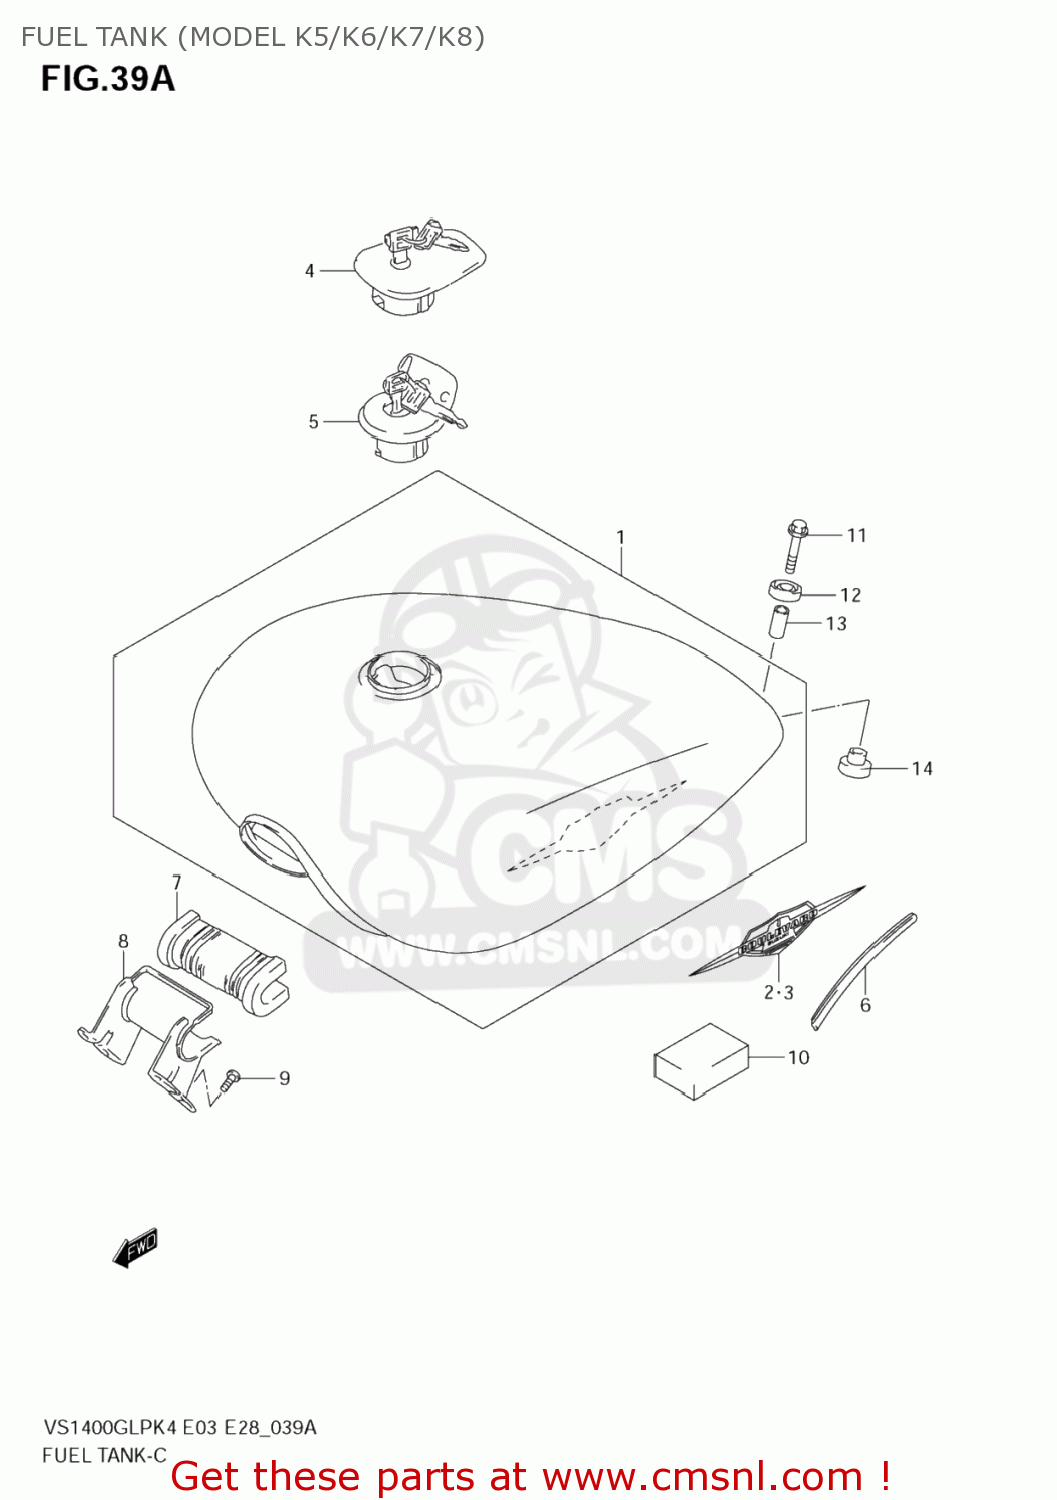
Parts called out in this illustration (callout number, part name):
1	TANK ASSY,FUEL(RED)
2	EMBLEM,FUEL TANK,R
3	EMBLEM,FUEL TANK,L
4	CAP SET,FUEL TANK
5	CAP SET,FUEL TANK
6	MOLDING
7	CUSHION,FUEL TANK FR
8	BRACKET,FUEL TANK FR
9	SCREW
10	CUSHION
11	BOLT
12	CUSHION
13	SPACER(6.5X9X22.5)
14	CUSHION
